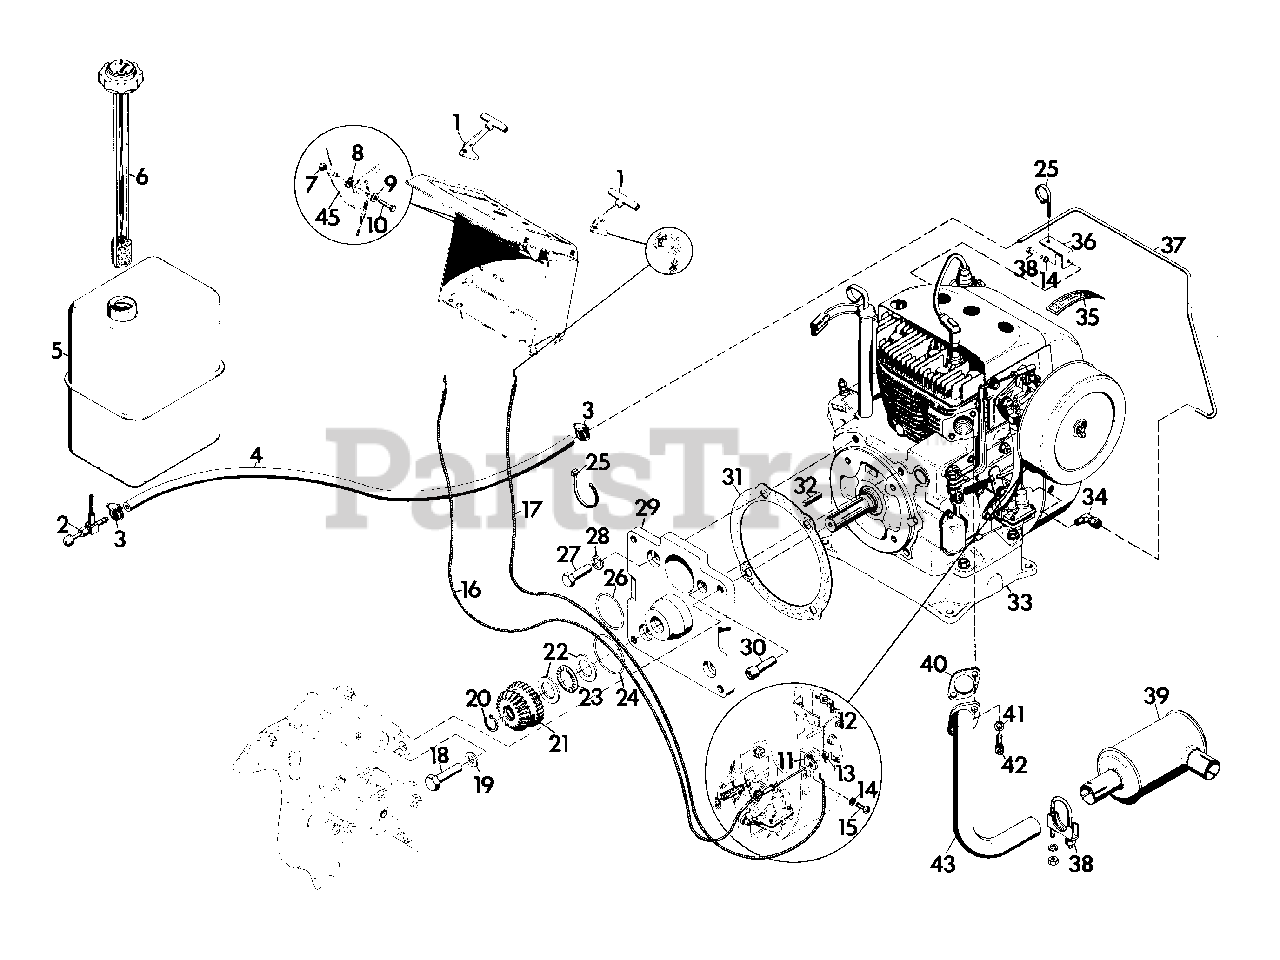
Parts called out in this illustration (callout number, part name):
1	ASSEMBLY, KNOB AND LEVER
2	VALVE, FUEL 90 DEG. REVERSE FLOW
3	CLAMP, HOSE
4	LINE, FUEL
5	TANK, FUEL
6	GAUGE, GAS
7	NUT, LOCK 1/4-28
8	WASHER, FRICTION
9	WASHER, SPRING
10	BOLT, HEX 1/4-28X.75
11	BRACKET
12	CLIP, SPEED
13	NUT, HEX 1/4-20
14	WASHER, LOCK 1/4 SP
15	SCREW, MACH. 1/4-20X.5 PAN HD
16	ASSEMBLY, THROTTLE CONDUIT
17	ASSEMBLY, CHOKE CONDUIT
18	BOLT, HEX 1/2-13X1.25
19	WASHER, LOCK 1/2 REG.
20	RING, RETAINING 1.125 SHAFT
21	GEAR, SPUR AND BEVEL, INPUT
22	RACE, BEARING THRUST 1.127X1.740X.060
23	BEARING, THRUST 1.127X1.740X.078
24	O-RING, 3.000X3.188X.094
25	TIE, CABLE
26	O-RING, 2.500X2.750X.125
27	BOLT, HEX 7/16-14X1.125
28	WASHER, LOCK 7/16 SP HEAVY
29	ADAPTOR, ENGINE
30	SCREW, CAP 7/16-14X1.0 SOCKET HEAD
31	GASKET, ADAPTOR
32	KEY, SQUARE .250X1.250
33	ENGINE, KOHLER 12 HP
34	ASSEMBLY, ELBOW 1/4 BALL SLEEVE
35	DECAL, AIR CLEANER INSTRUCTION
36	BRACKET, FUEL LINE SUPPORT
37	CONNECTOR TO PUMP FUEL LINE
38	BOLT, HEX 1/4-20X.750
39	MUFFLER, EXHAUST
40	GASKET, EXHAUST
41	WASHER, LOCK 5/16 REG.
42	SCREW, CAP 5/16-18X.75 SOCKET HD
43	HEADER, EXHAUST
44	CLAMP, MUFFLER
45	BRACKET, MOUNTING
NS	NUT, LOCK 10-32
NS	SCREW, MACHINE 10-32X.50 PHD
